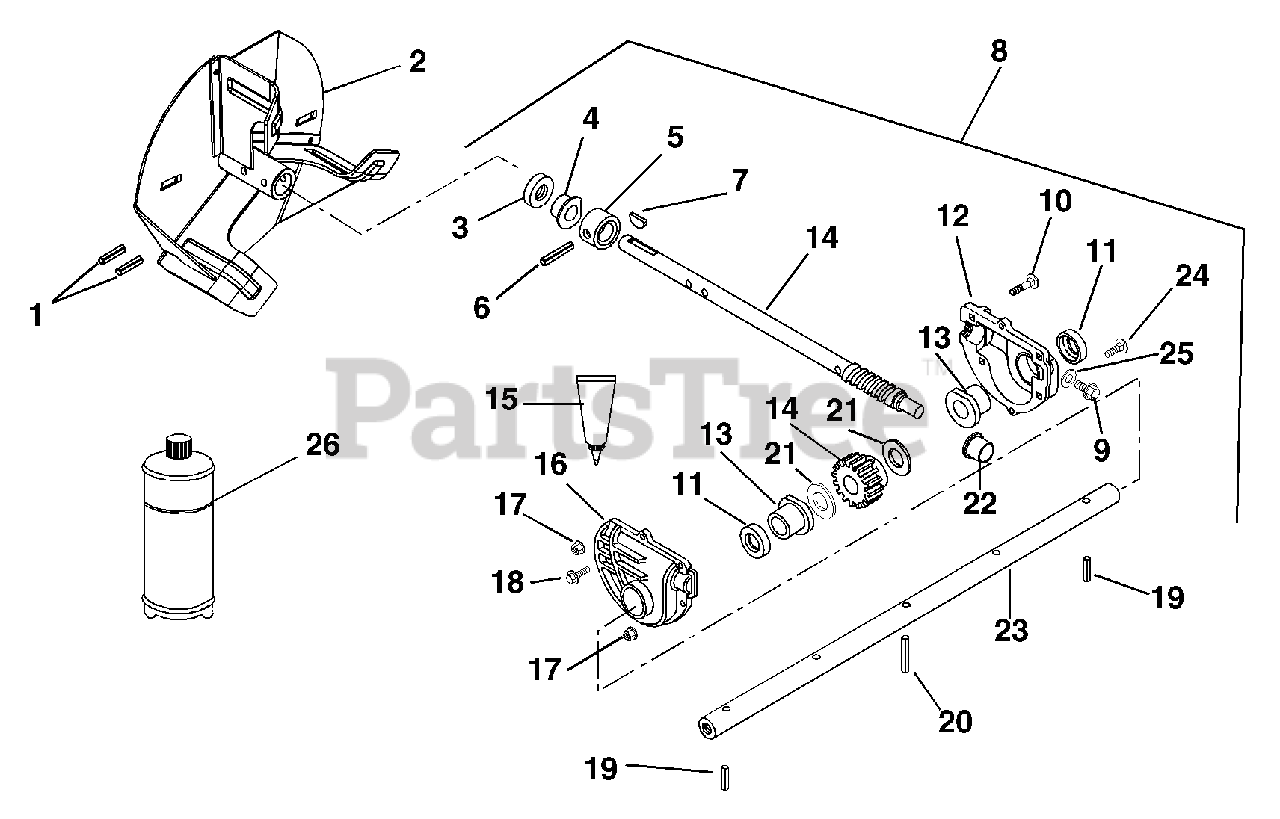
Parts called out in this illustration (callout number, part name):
1	PIN-ROLL .250X1.75
2	IMPELLER - .75 ID X 12" OD
3	SEAL-OIL .750X1.375X.250
4	BSHG-FLG .750X1.000X.750X1.250
5	THRUST COLLAR
6	PIN-GRV .188X1.25 TP A
7	KEY-WDRF .188X.875X.375 SAE11
8	CASE, GEAR-LARGE BORE-28"-ALUM
9	@SCR-TAP .38-16X.50 HWH TR YWZ
10	@BLT-RDHDSQNK .25-20X1.25 G5YZ
11	SEAL-OIL 1.000X1.375X.250
12	CASE, GEAR-LH-LARGE BORE-ALUM.
13	BSHG-FLG 1.00X1.12
14	WORM SHAFT & GEAR ASSY
15	LOCTITE GASKET 518--850CC CRTG
16	CASE, GEAR-RH-LARGE BORE-ALUM.
17	@NUT-SPNLK-FLG .25-20 YWZC
18	SCR-TAP 10-24X.75 HWH TR YWZC
19	PIN-ROLL .188X1.50
20	PIN-GRV .313X1.44 TP C
21	WSHR-HRD-THRS 1.007X1.542X.062
22	BSHG-FLG .502X1X.750
23	SHAFT, RAKE - 28"
24	@BLT-RDHDSQNK .25-20X1.00 G5YZ
25	WSHR-FIBER .437X.656X.032
26	ARIENS 16 OZ.BOTTLE OF L2 LUBE
